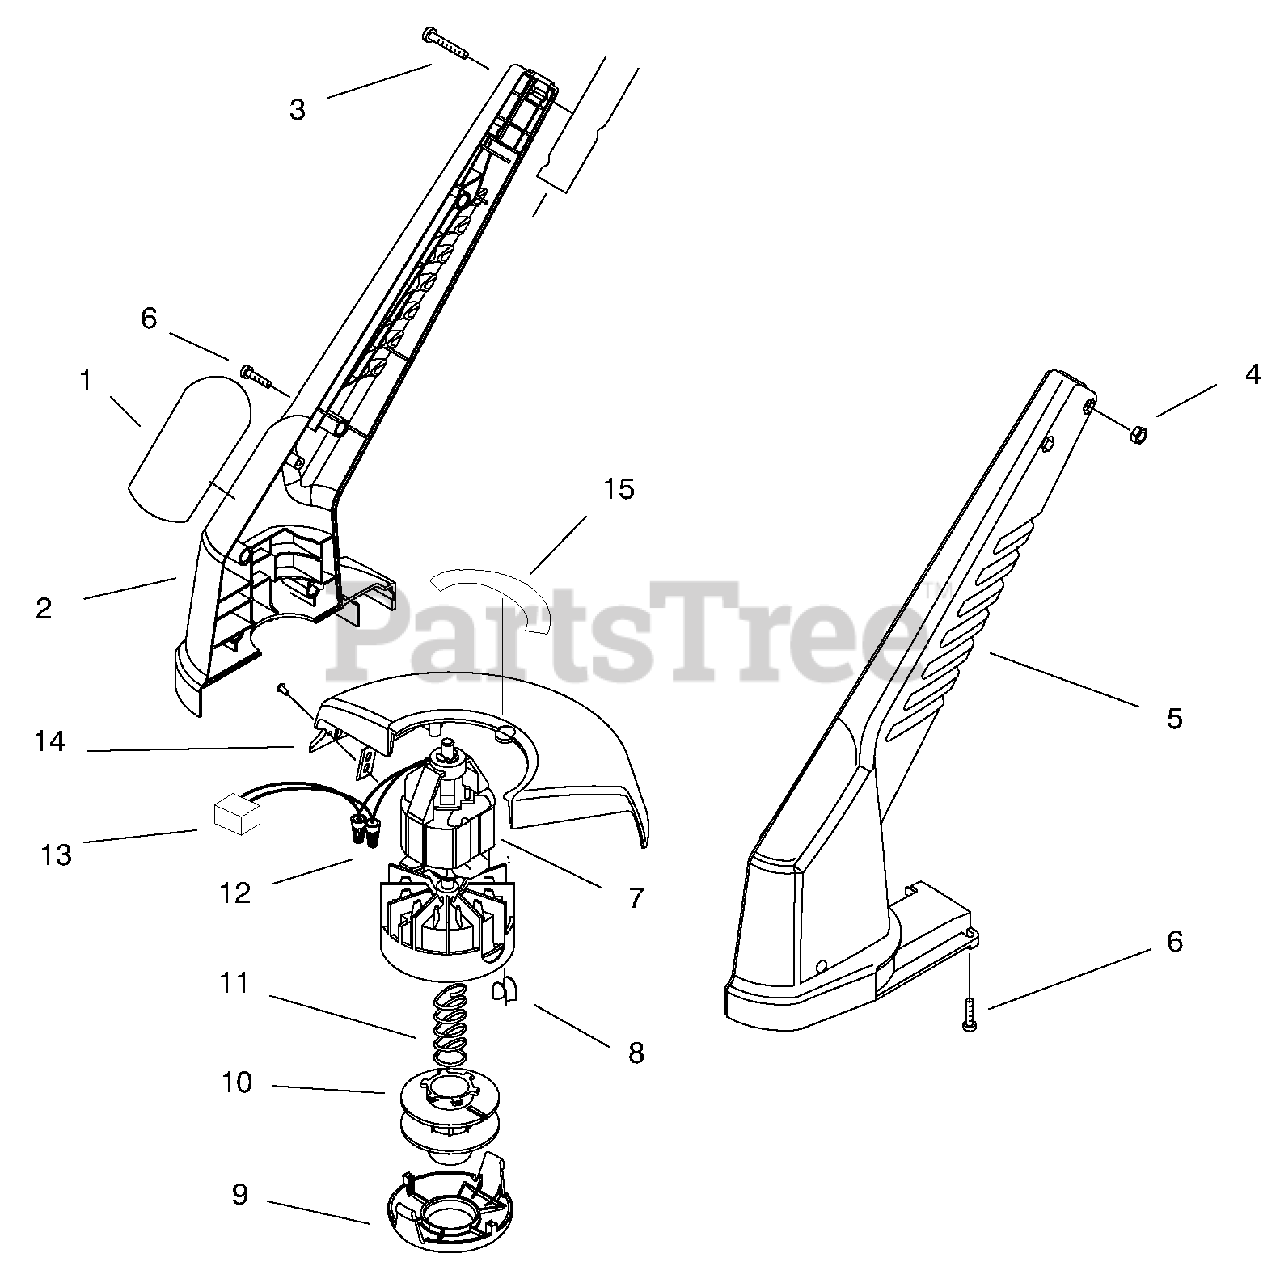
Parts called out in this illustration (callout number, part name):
1	Decal-25CM Trimmer
2	Housing R.H.
3	Screw-Pan Hd.
5	Housing L.H.
6	Screw-Pan Hd.
7	Motor Assembly-Trimmer (Incl. Ref. #8)
12	Connector-Wire Nut
14	Shield Assembly
15	Decal-Sheild
